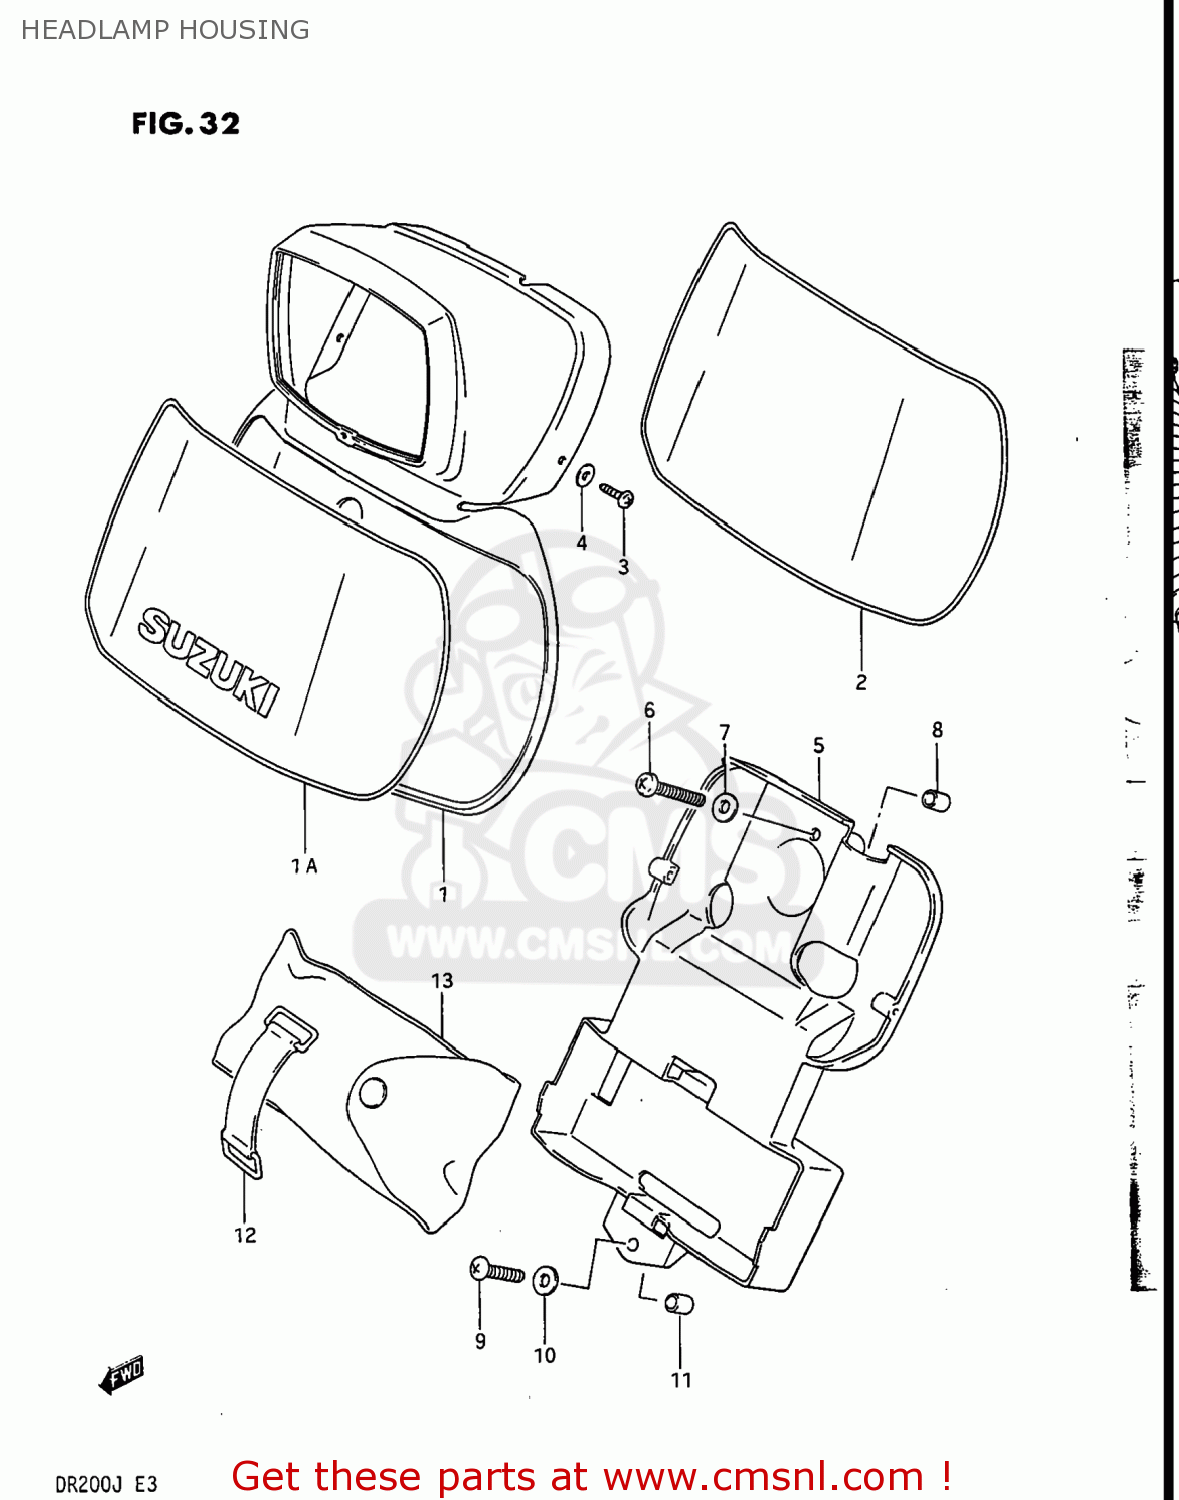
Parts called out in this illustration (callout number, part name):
1	HOUSING,HEADLAMP
1A	TAPE SET,HEADLAMP COVER
2	TAPE SET,HEADLAMP COVER
3	TAPPING SCREW
4	WASHER 4MM
5	HOLDER,TOOL
6	SCREW
7	WASHER
8	SPACER (6.8X10X27.4)
9	SCREW
10	WASHER
11	SPACER (6.8X10X10)
12	BAND
13	TOOL SET
